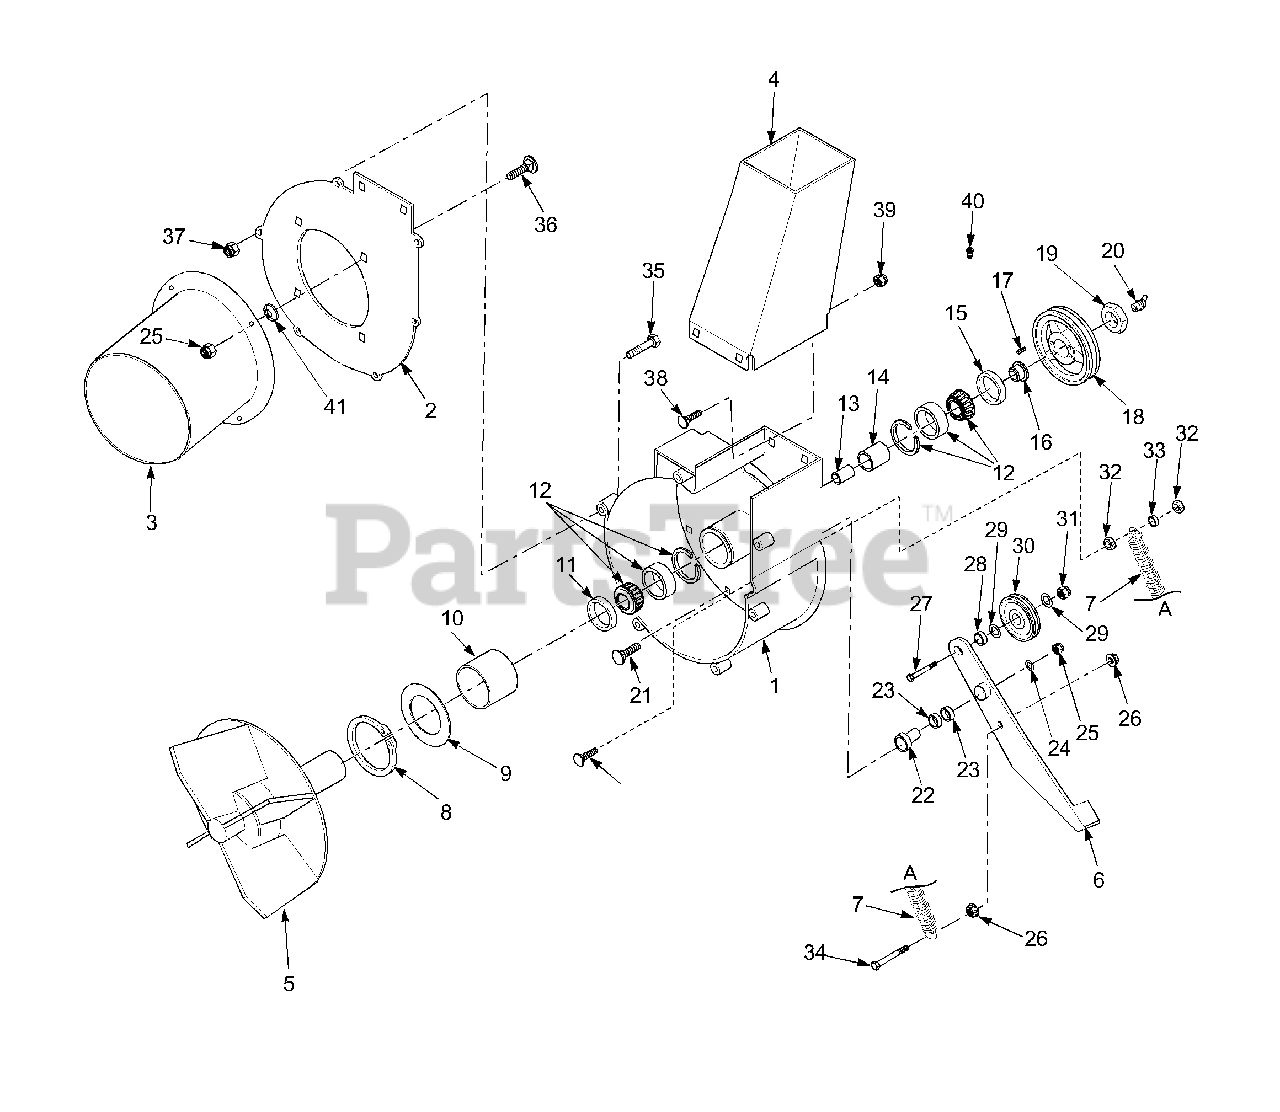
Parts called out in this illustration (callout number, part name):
1	Blower Housing, Rear
2	Blower Housing, Front
3	Inlet
4	Outlet
6	Idler Arm, Weldment
7	Spring
8	Ring, Retaining 2.5 ext.
9	Washer, Retainer
10	Bushing, Oilite 2.505 ID
11	Seal, 2.00 OD x 1.50 Bore
12	Bearing Assembly
13	Spacer, Inside
14	Spacer, Outside
15	Seal, 2.00 OD x 1.625 Bore
16	Bushing
17	Key, 1/4 x .874 Woodruff
18	Pulley, 5.25 OD
19	Nut, 1-1/16 - 18 LH Thread
20	Grease Fitting, 65 degree angle
21	Bolt, Carriage 3/8-16 x 2.5"
22	Idler Arm w/pivot
23	Bearing
24	Flatwasher 3/8"
25	Nut, Elastic Stop 3/8-16
26	Nut, Serr. Flng. 3/8-16
27	Bolt, HH 3/8-16 x 2.25"
28	Spacer
29	Flat Washer 3/8"
30	Pulley, 3.0" diameter
31	Nut, Elastic Stop 3/8-16
32	Nut, Serr. Flng. 3/8-16
33	Spacer
34	Bolt, HH 3/8-16 x 1.5"
35	Bolt, HH 5/16-18 x 1.5"
36	Bolt, Carriage 3/8-16 x 1.0
37	Nut, Elastic Stop 5/16-18
38	Bolt, Carriage 1/4-20 x 1.0
39	Nut, Elastic Stop 1/4-20
40	Relief Fitting
41	Push Nut, 3/8 Thread
